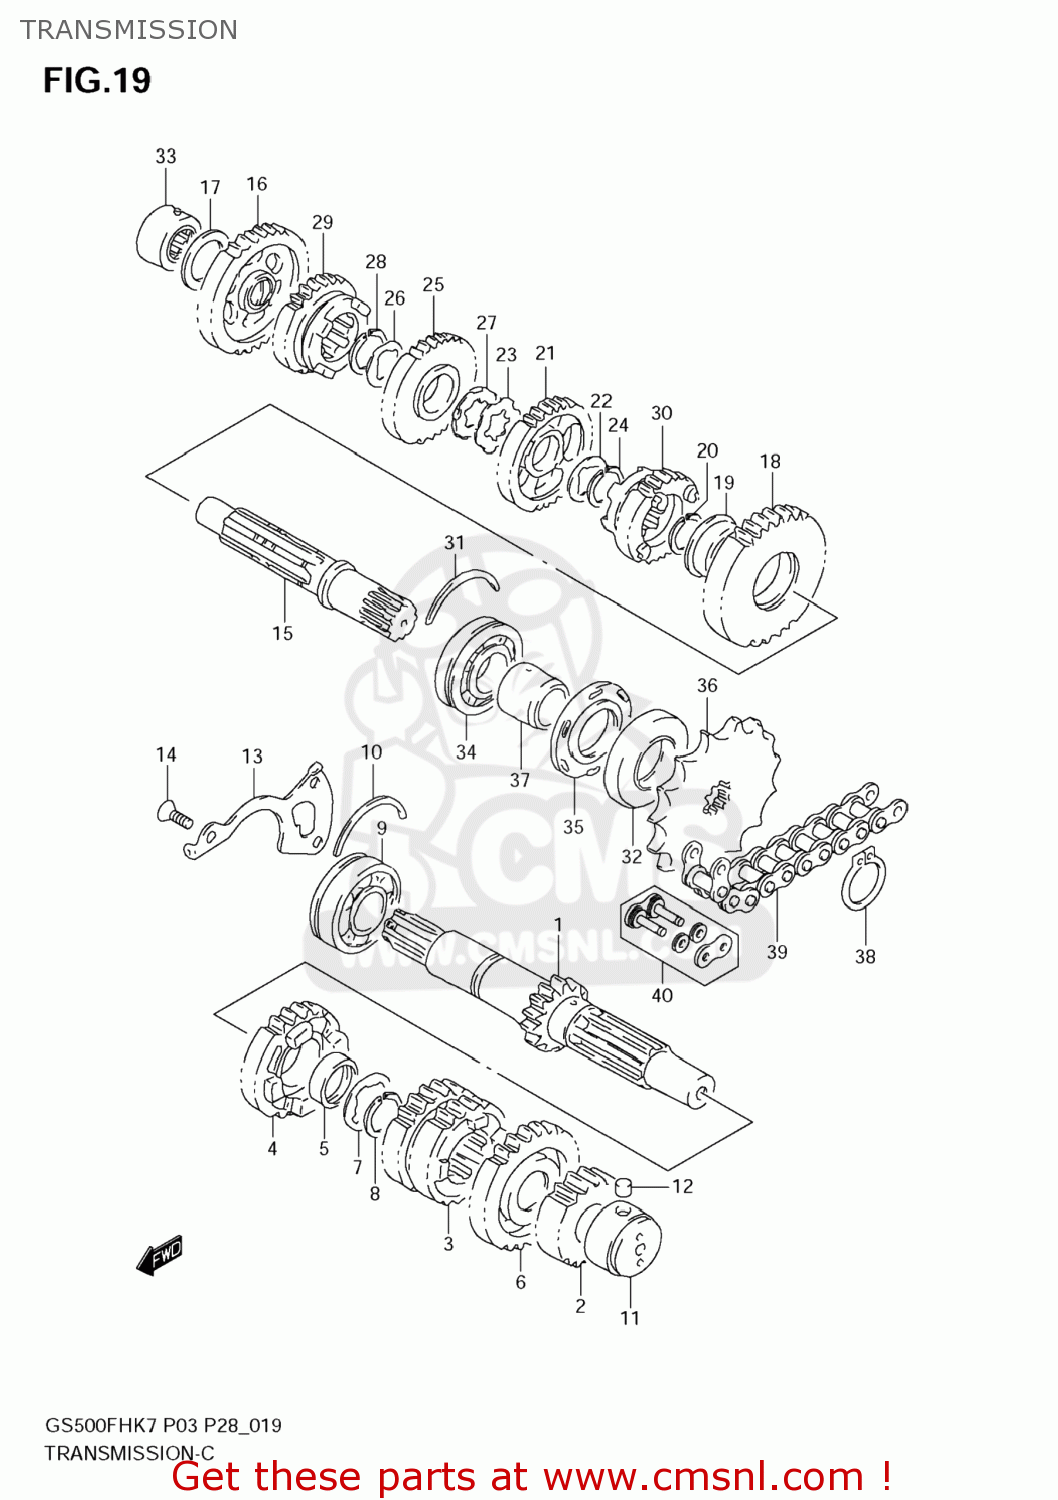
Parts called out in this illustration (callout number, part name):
1	SHAFT,COUNTER
2	GEAR,2ND DRIVE(NT:18)
3	GEAR,3RD & 4TH
4	GEAR,5TH DRIVE(NT:26)
5	BUSH
6	GEAR,6TH DRIVE
7	SHIM(25X34X1)
8	CIRCLIP
9	BEARING(25X62X17)
10	C RING
11	BEARING(20X34X20)
12	PIN
13	PLATE,COUNTERSHAFT BEARING
14	SCREW(6X16)
15	SHAFT,DRIVE
16	GEAR,1ST DRIVEN
17	SHIM(20X34X1)
18	GEAR,2ND DRIVEN.NT:32)
19	BUSH
20	CIRCLIP
21	GEAR,3RD DRIVEN
22	WASHER,LOCK
23	WASHER,LOCK
24	CIRCLIP
25	GEAR,4TH DRIVEN
26	WASHER,LOCK
27	WASHER
28	CIRCLIP
29	GEAR,5TH DRIVEN(NT:25)
30	GEAR,6TH DRIVEN(NT:23)
31	C RING
32	SEAL,OIL(32X62X7)
33	BEARING(20X34X17)
34	BEARING(25X62X17)
35	SEAL,OIL(32X62X5.5)
36	SPROCKET,ENGINE(16T)
37	SPACER,ENGINE SPROCKET
38	CIRCLIP
39	CHAIN, DRIVE (DID520VM, 110LE
40	JOINSET, CHAIN
